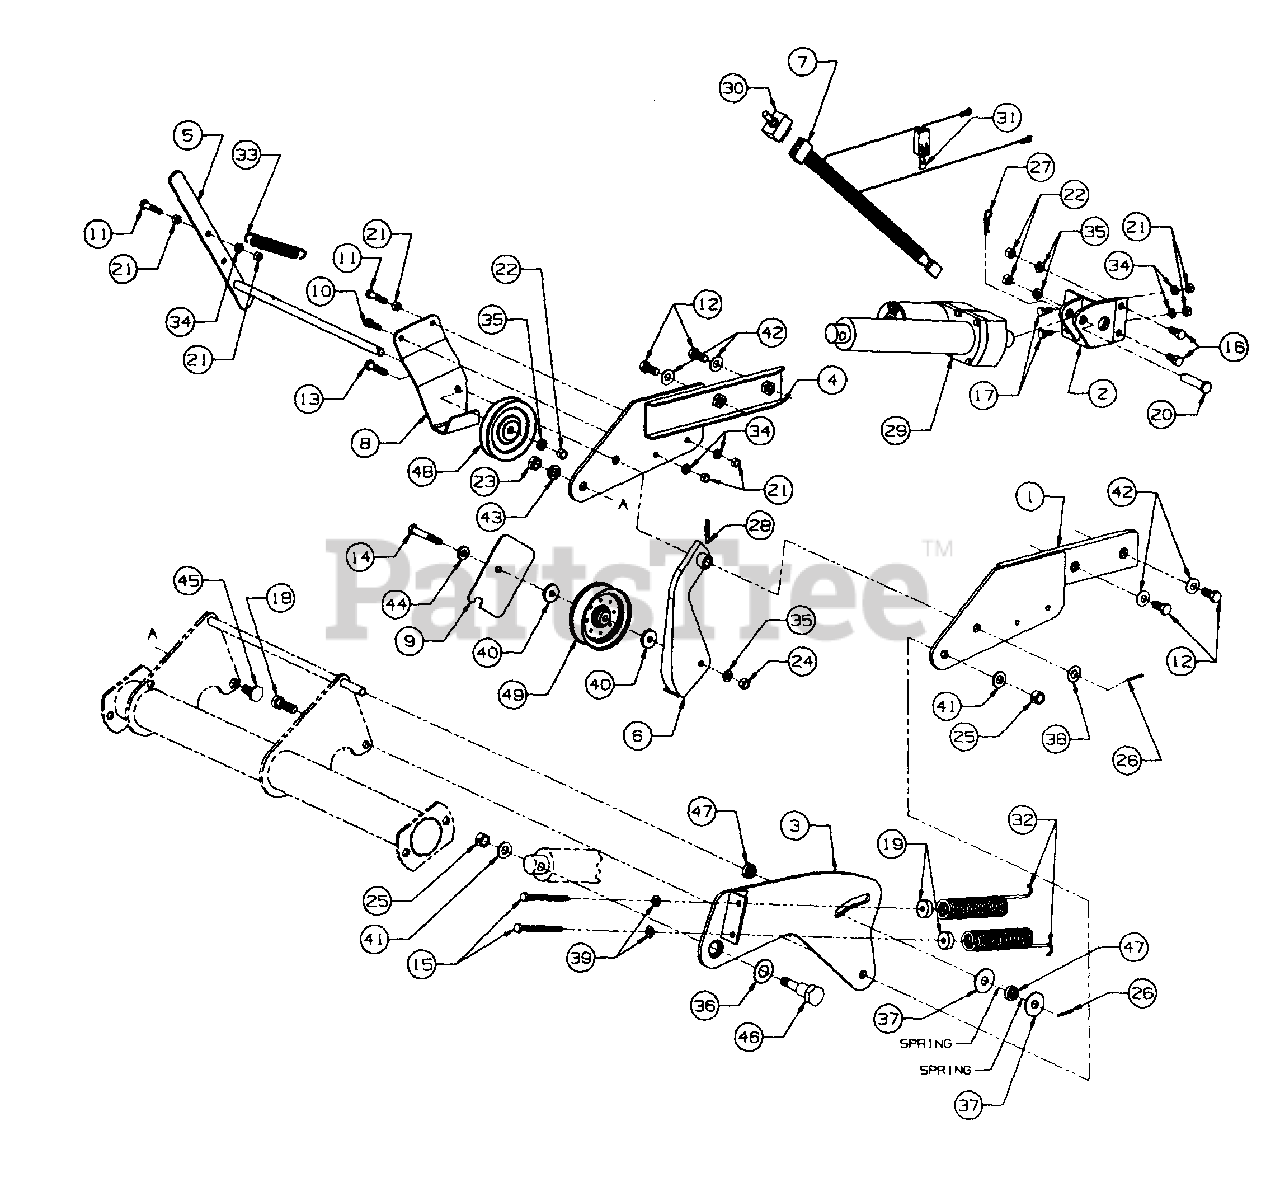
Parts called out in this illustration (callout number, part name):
11	Screw, Hex Cap, 5/16-18 X 1.50 Lg
12	Screw, Hex Cap, 7/16-14 X 1.0 Lg
13	Screw, Hex Cap, 3/8-16 X 1.50 Lg GR5
14	Screw, Hex Cap, 3/8-16 X 2.50 Lg GR5
15	Screw, Hex Cap, 5/16-18 X 3.50 Lg
16	Screw, Hex Cap, 3/8-16 X .75 Lg GR5
17	Screw, Hex Cap, 5/16-18 X .75 Lg GR5
18	Screw, Hex Cap, 1/2-13 X 1.50 Lg GR5
19	Insert, Spring
20	Pin, Clevis, .50 Dia X 2.19 Lg
21	Nut, Hex, 5/16-18
22	Nut, Hex, 3/8-16
23	Nut, Hex Jam, 1/2-20
24	Nut, Hex, 3/8-16
25	Nut, Hex Center Lock, 1/2-13 GR5
26	Pin, Cotter, 1/8 Dia X 1.0 Lg
27	Cotter, Hairpin
28	Pin, Spring Roll, 3/16 Dia X 1.5 Lg
29	Cylinder, Electric Lift
30	Switch, Toggle Lift
31	Fuse, 30 Amp
32	Spring, Helper
33	Spring, Extension, .75 Dia X 5.06 Lg
34	Washer, Lock, 5/16
35	Washer, Lock, 3/8
36	Washer, Flat, .76 X 1.49 X .06 Thk
37	Washer, Flat, .51 X 1.50 X .07 Thk
38	Washer, Flat, .510 X 1.00 X .06 Thk
39	Washer, Flat, 5/16
40	Washer, Flat, .390 X 1.12 X .187 Thk
41	Washer, Flat, .510 X 1.00 X .12 Thk
42	Washer, Bell, .45 X 1.00 X .062 Thk
43	Washer, Lock, 1/2
44	Washer, Flat, .406 X .812 X .134 Thk Hdn
45	Bolt, Shoulder, .62 Dia X .30 Lg
46	Bolt, Shoulder, .75 Dia X 1.10 Lg
47	Spacer, .510 ID X .875 OD X .275 Lg
48	Pulley, V-Idler, 4.0 OD
49	Pulley, Flat Idler, 3.12 OD
